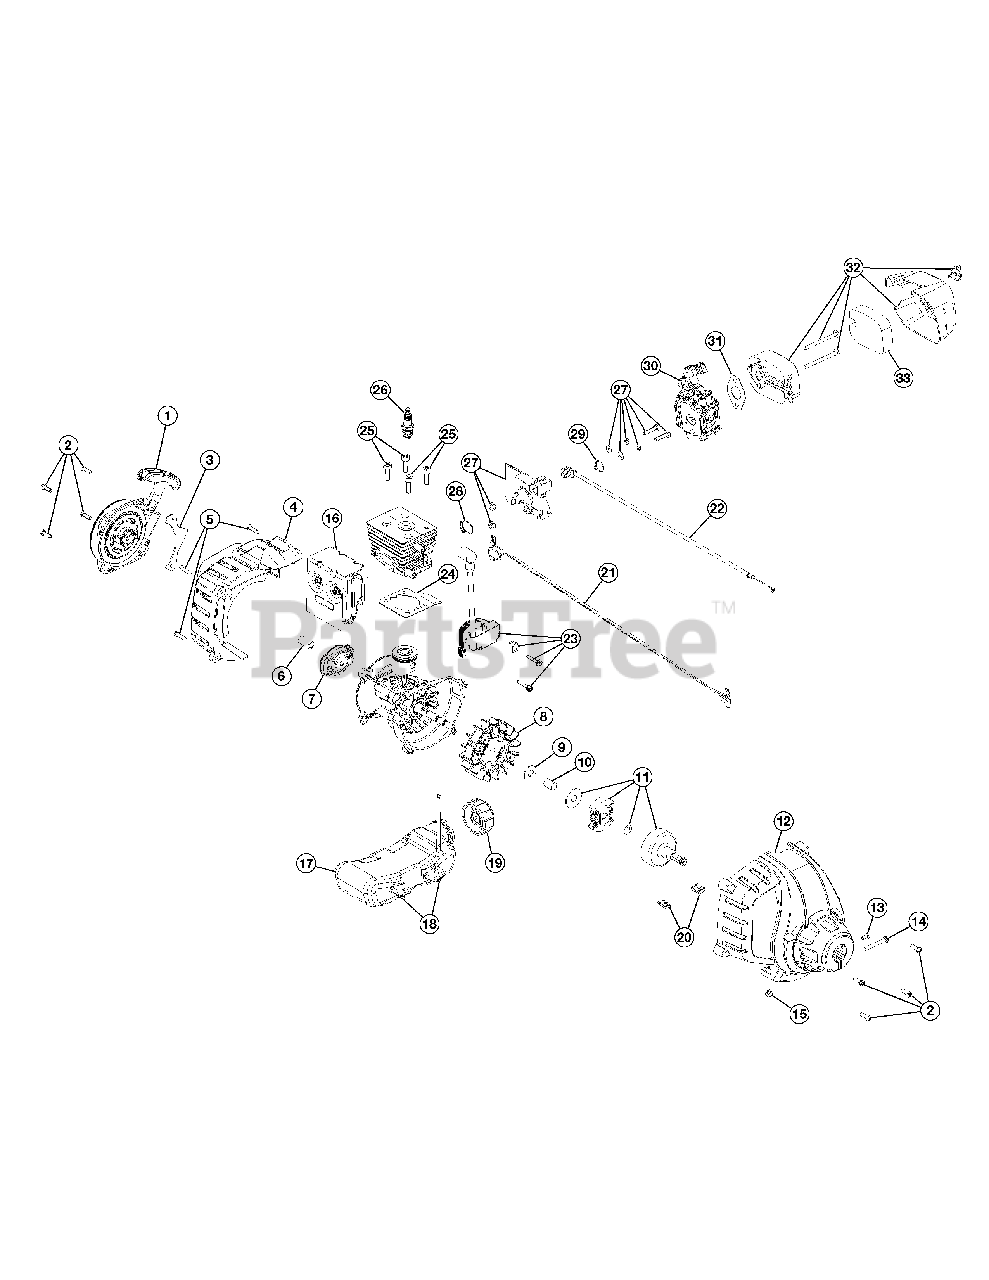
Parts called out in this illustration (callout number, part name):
1	Starter Assembly (Incl. 2 & 3)
2	Starter Screw
3	Starter Assembly Guard (Incl. 2)
4	Rear Engine Cover (Incl. 5)
5	Cover Screw
7	Pawl Assembly
8	Flywheel Assembly
11	Clutch Assembly
12	Clutch Cover Assembly (Incl. 2, 13 - 15 and 20)
13	Anti-rotation Screw
14	Clamp Screw
15	Clamp Nut
16	Muffler Assembly
17	Fuel Tank Assembly (Incl. 18 and 19)
20	U-shaped Nut
21	Lead Wires
22	Throttle Cable
23	Module Assembly
24	Cylinder Gasket
25	Cylinder Bolt
26	Spark Plug
27	Insulator Assembly (Incl. 28 and 29)
28	Insulator O-Ring
29	Carburetor O-Ring
30	Carburetor
31	Carburetor Gasket
32	Air Cleaner Assembly (Incl. 33)
33	Air Cleaner Filter
